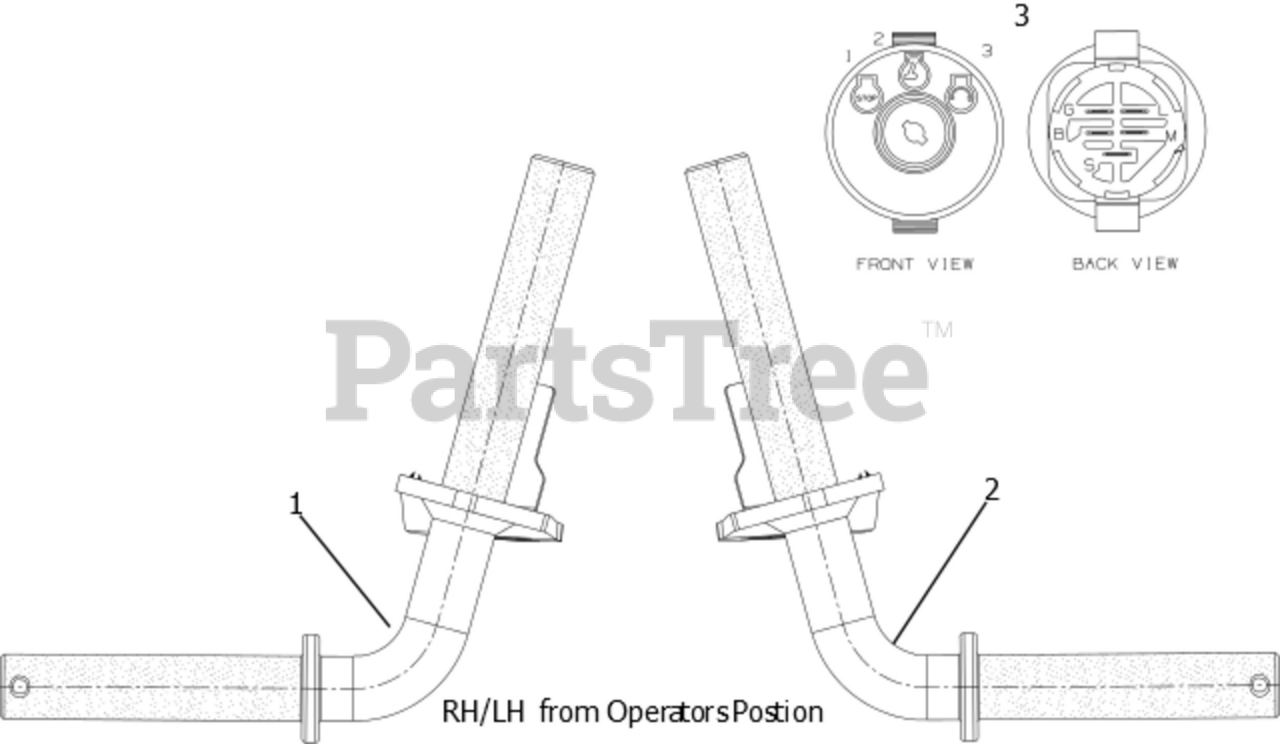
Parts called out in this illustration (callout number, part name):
1	FRONT AXLE ASSEMBLY (RH)
2	FRONT AXLE ASSEMBLY (LH)
3	3 POSITION KEY SWITCH
